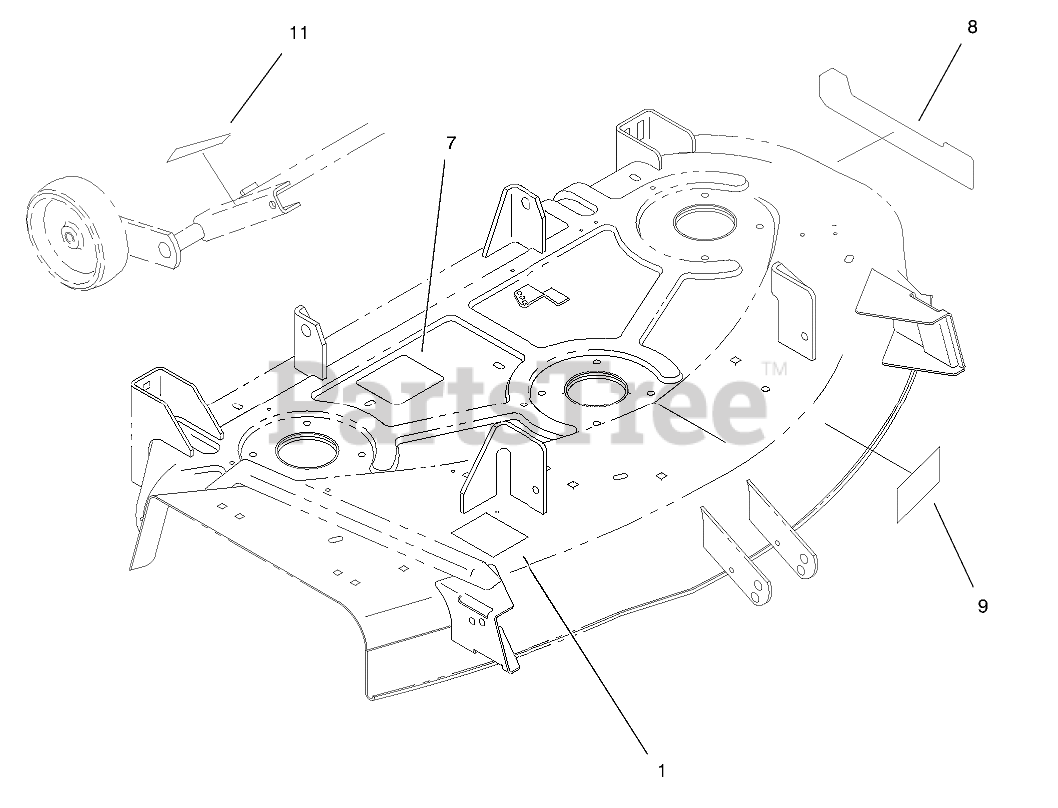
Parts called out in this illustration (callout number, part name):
1	DECAL-BELT ROUTING
7	DECAL - BELT ROUTING
8	Decal-Deck (Only On: 78358)
9	DECAL-ADJUSTMENT, WHEEL
11	Decal-Height Of Cut (Only On: 78357, 78358)
